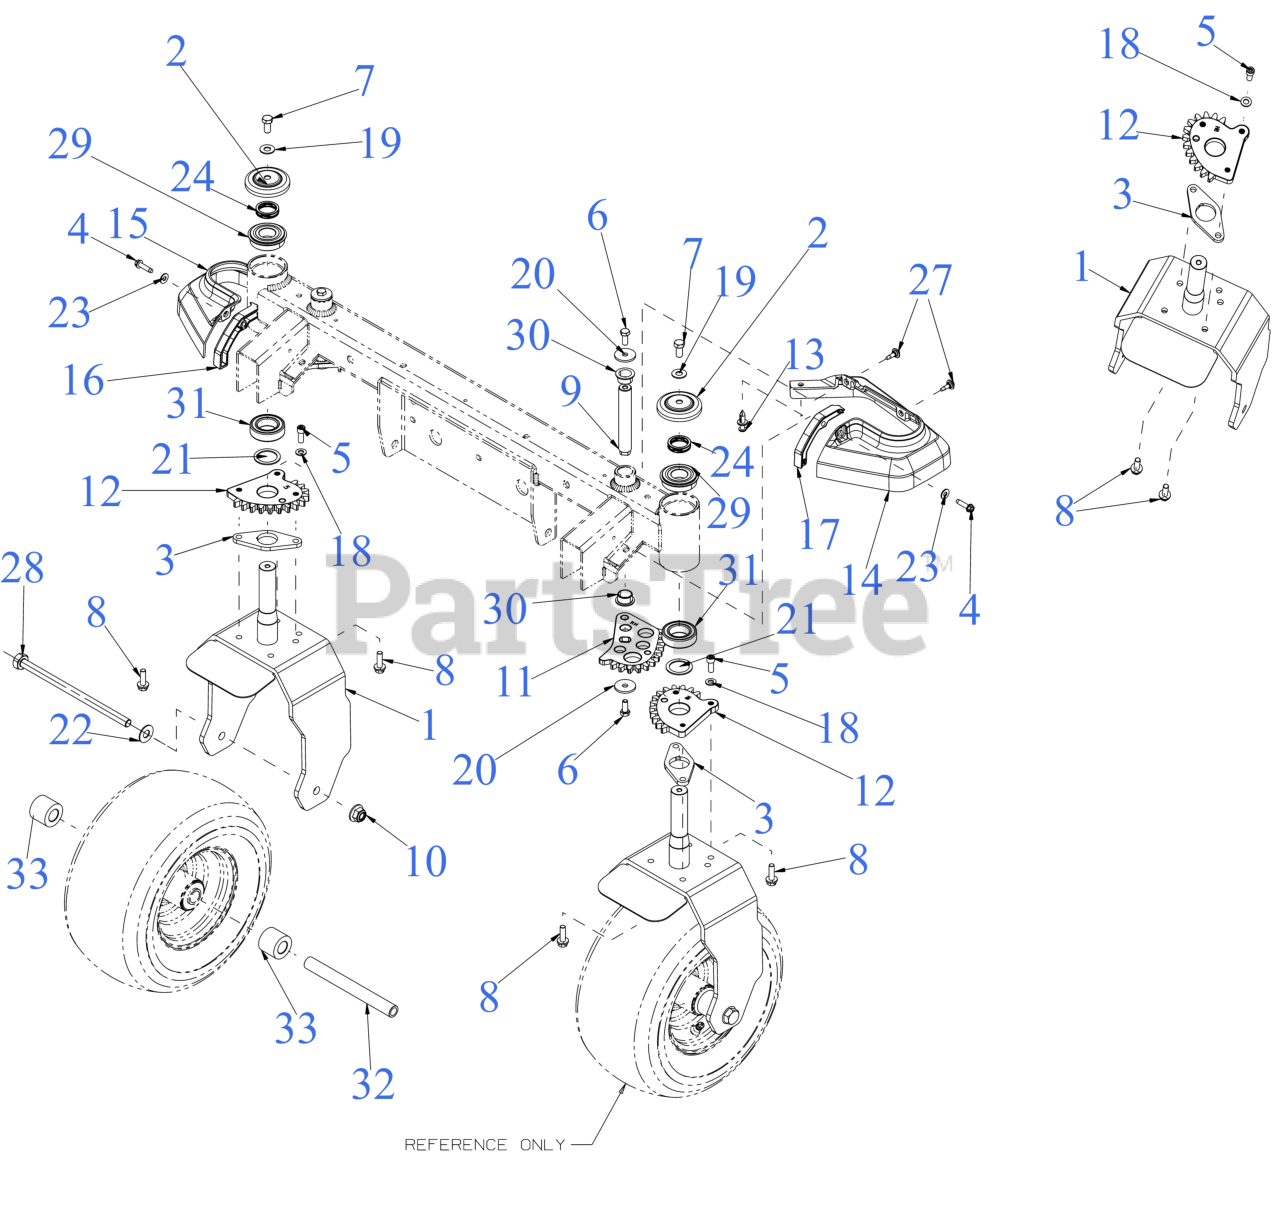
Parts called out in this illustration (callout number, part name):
1	CASTER WHEEL YOKE
3	CASTER GEAR PLATE
4	SCREW 1/4-20 x 1.00
5	SCREW 5/16-18 x .625
6	SCREW 5/16-18 x .750
7	SCREW 3/8-16 x .75 GR 5
8	SCREW 5/16-18 x 1 GR5
9	STEERING GEAR PIVOT SHAFT
11	STEERING GEAR 12T
12	SPUR GEAR 13T
13	PLASTIC RIVET
14	STEERING GEAR COVER (RH)
15	STEERING GEAR COVER (LH)
16	GEAR COVER EXTENSION (LH)
17	GEAR COVER EXTENSION (RH)
18	FLAT WASHER
19	FLAT WASHER
20	WASHER-5/16 x 1.25X 1.27
21	FLAT WASHER 1.187X1.56X.062
22	FLAT WASHER
23	FLAT WASHER
24	WAVE WASHER
27	SHOULDER SCREW M6-1 .368 X.115
28	SCREW-1/2-13X8.5 GR5 FLG RZF-SX
29	BALL BEARING 25X52X15
30	FLANGE BEARING .75x.875x.50
31	BALL BEARING (LOWER FRONT AXLE)
32	CASTER AXLE SPACER
33	CASTER WHEEL SPACER
